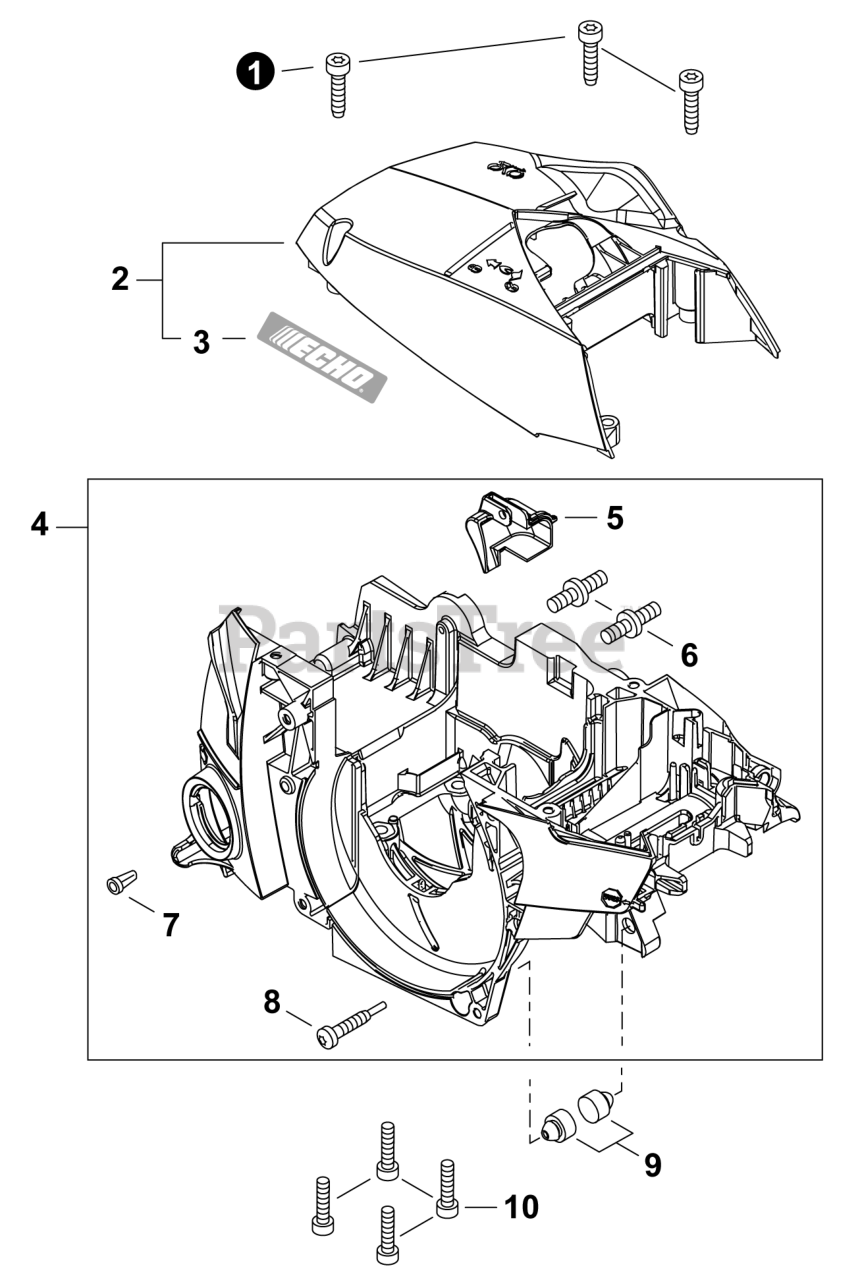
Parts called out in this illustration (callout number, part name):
1	BOLT, TORX 5x20
2	COVER, ENGINE
3	LABEL - ECHO
4	HOUSING ASSY, ENGINE
5	DUCT, AIR
6	BOLT, STUD 8
7	VENT ASSY
9	CUSHION
10	BOLT 5x40
